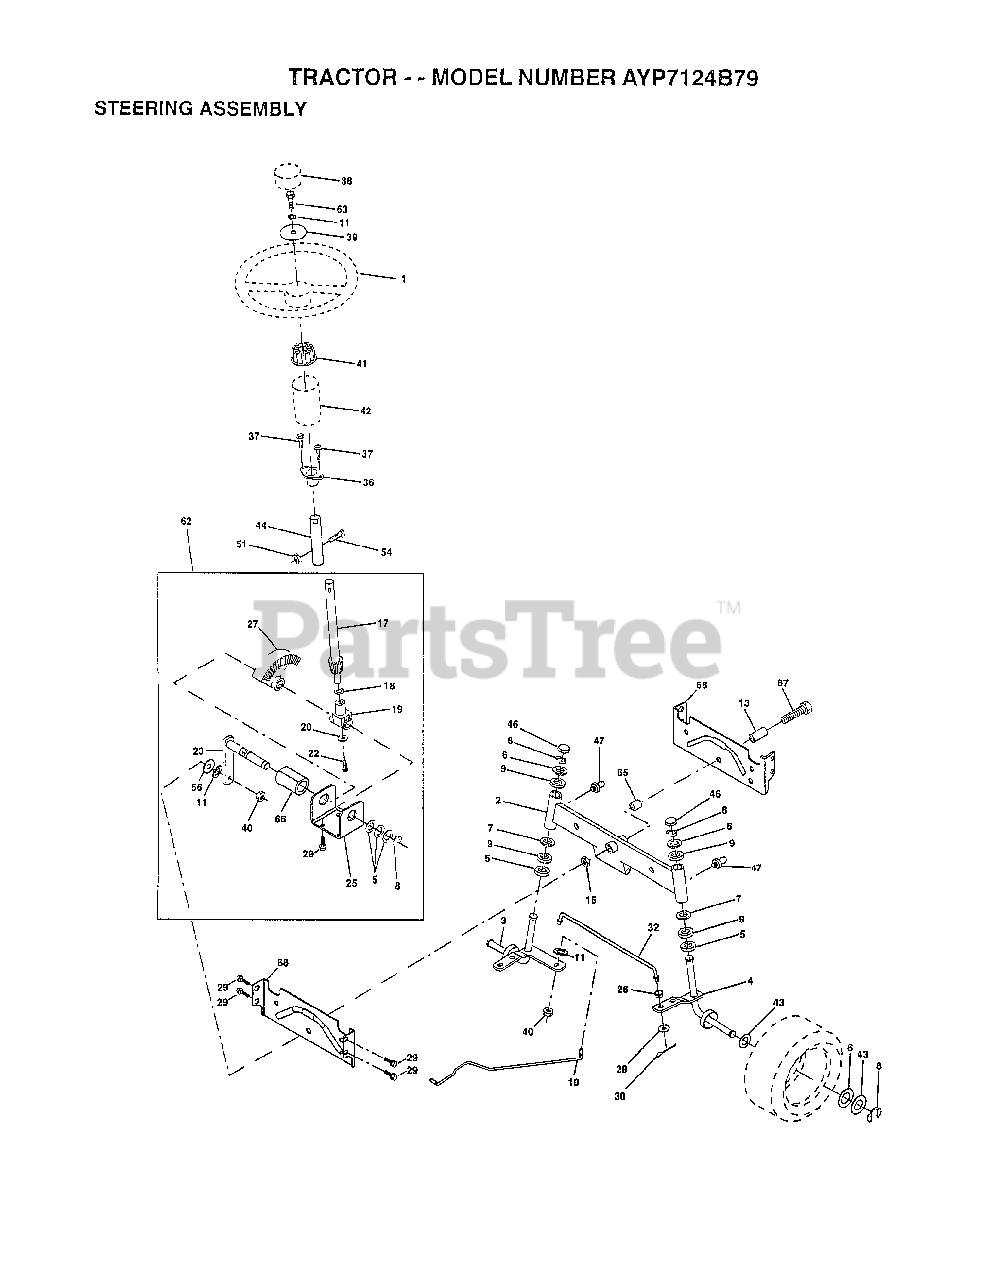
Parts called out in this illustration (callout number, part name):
1	WHEEL STR AYP BLK
2	AXLE ASM
3	SPINDLE.ASM.LH
4	"SPINDLE ASM,RH"
5	WASHER .T
6	WASHER
7	WASHER
8	RING
9	COL. SRTG. BEAR.
10	DRAGLINK-STAMPED
11	LOCKWASHER
13	BEARING AXLE
14	BOLT HEX 5/8-11
15	"NUT-LOC,FLANGE LT"
16	AXLE PIN
17	SHAFT ASM STEERIN
18	THRUST WASHER
19	SUPPORT.SHAFT
21	LOCKWASHER
22	SCREW.SCKTHD.CAP
25	BRKT-STEERING
26	BUSHING.DRAGLINK
27	GEAR SECTOR
28	WASHER
29	SCREW
30	COTTER PIN
32	TIE ROD
36	BUSHING.STEERING
37	"SCREW-TT,10-32 FL"
38	CAP STEER AYP
39	WASHER T
40	GRIPCO NUT
41	ADAPTER LT
42	BOOT.STEER.PL
43	WASHER
44	EXT SHAFT STEERIN
46	CAP
47	ZERK M
51	NUT
54	BOLT
62	KIT STEERING ASM
63	BOLT
65	SPACER AXLE
66	"BEARING-ARM,PITMA"
67	BOLT
68	BRACE AXLE
